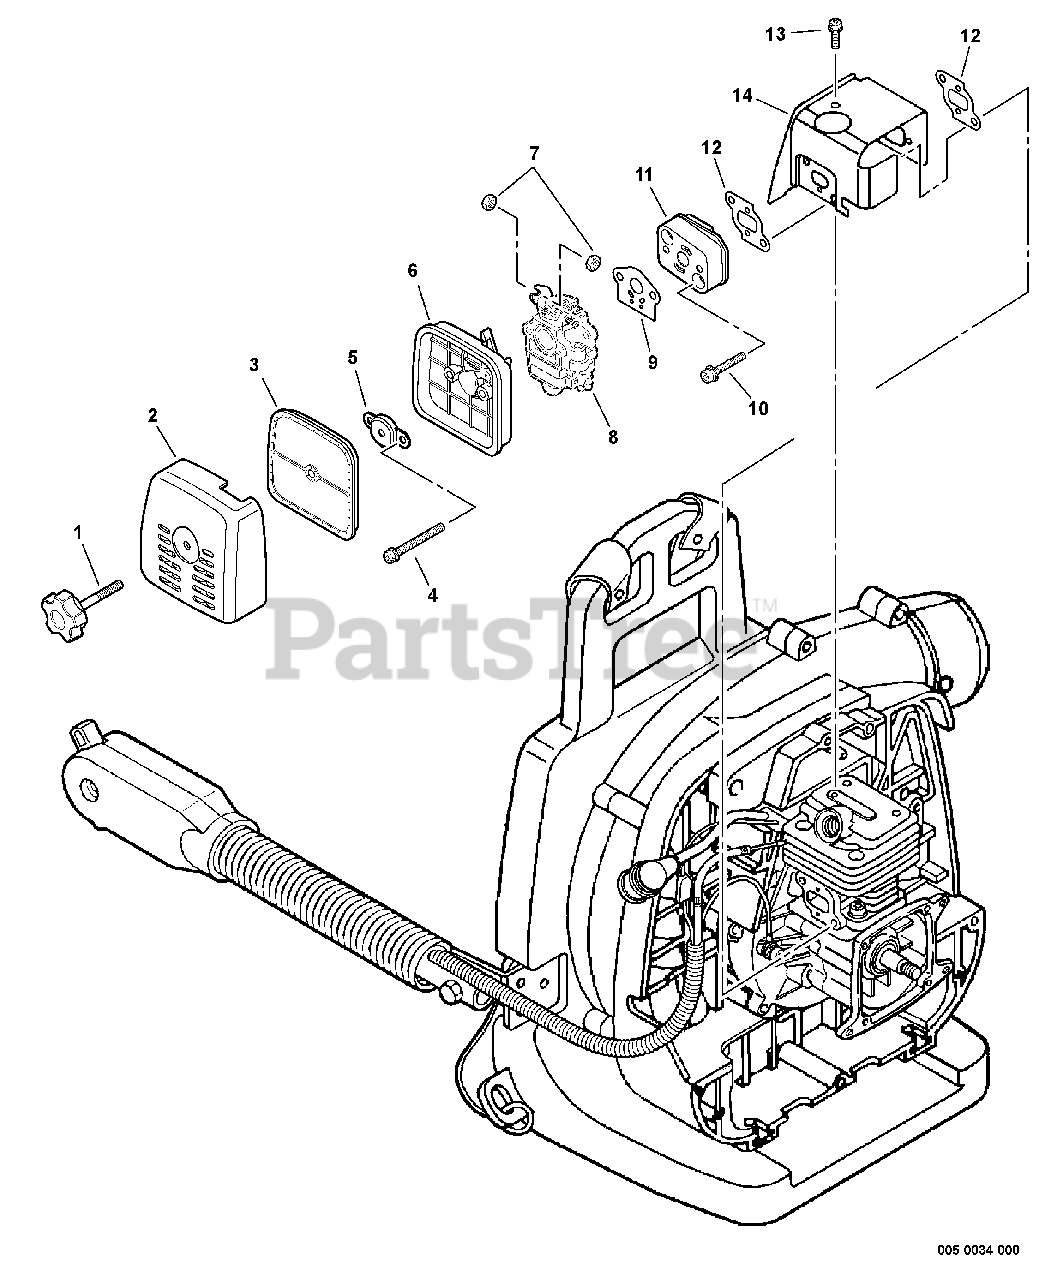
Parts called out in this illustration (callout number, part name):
1	THUMBSCREW
2	COVER, AIR FILTER
3	FILTER, HEAVY-DUTY AIR
4	PLATE, PREVENT
5	SCREW 5×60
6	CASE, AIR FILTER
8	CARBURETOR
9	GASKET, CARBURETOR
10	INSULATOR, INTAKE
11	BOLT 5×25
12	GASKET, INTAKE
13	COVER, CYLINDER
14	SCREW 5×10
